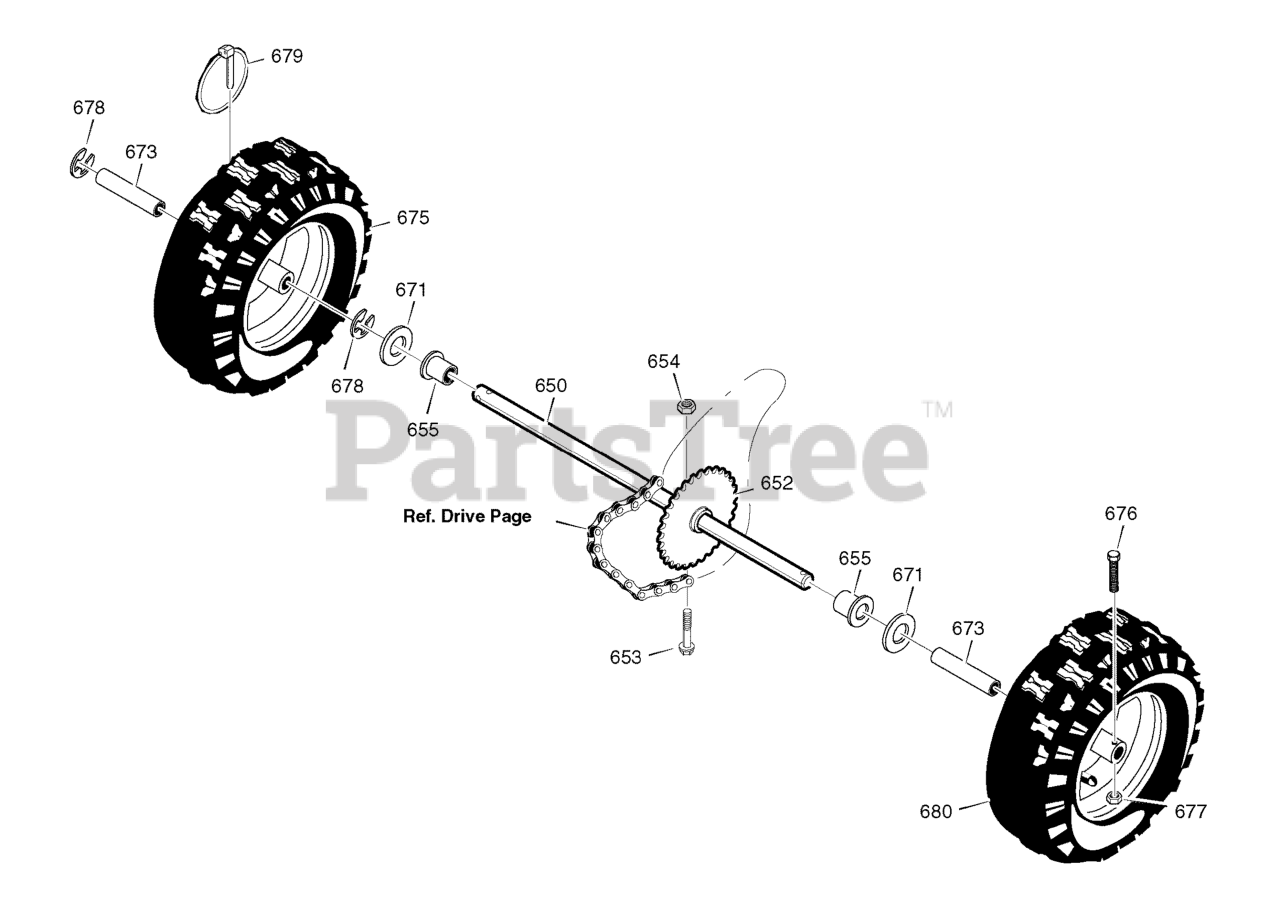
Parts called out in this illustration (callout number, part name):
650	SHAFT, AXLE
652	SPROCKET & HUB
653	SCREW, 1/4-20 X 1.75
654	NUT, 1/4-20 HEX NYLOCK
655	BEARING, AXLE
671	FLATWASHER
673	BUSHING, WHEEL
675	TIRE & RIM, RIGHT
676	SCREW, 1/4-20 X 1.75 HH
677	NUT, 1/4-20 HEX NYLOCK
678	RING, RETAINER
679	PIN, KLIK 0.25 X 1.38 DIA
680	TIRE & RIM, LEFT
